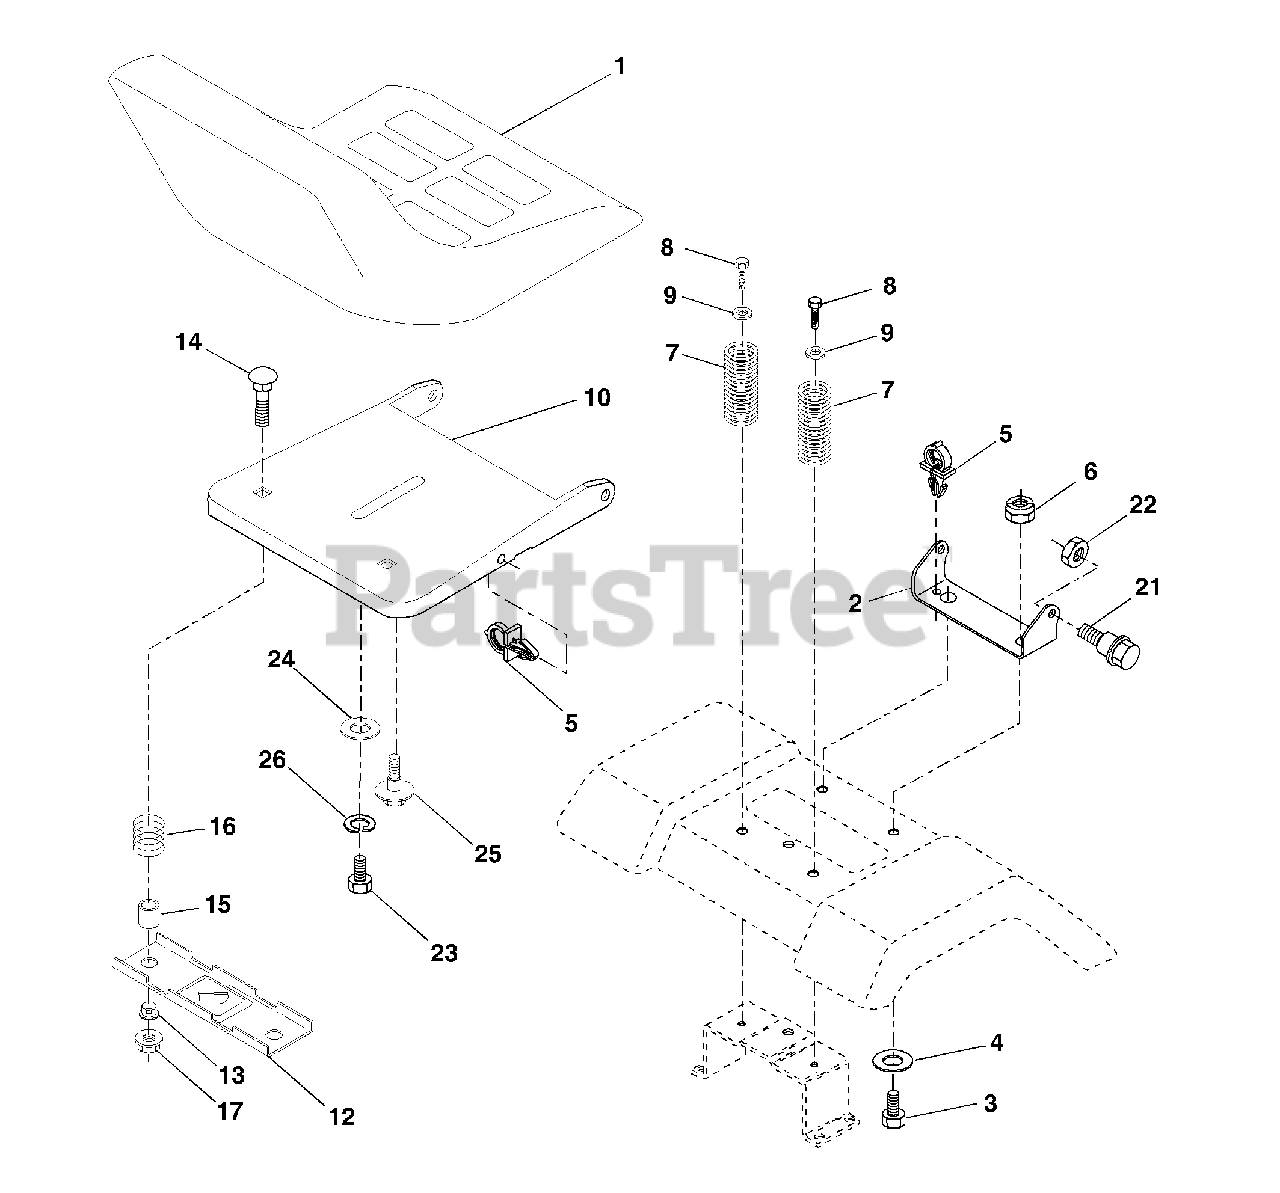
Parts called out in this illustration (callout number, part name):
1	Seat
2	Bracket Pnt Pivot Seat(blk )
3	Bolt
4	Washer 13/32 x 1 x 10 Ga
5	Clip Push-In Hinged
6	Nut
7	Spring Seat Cprsn 2 250 Blk Zi
8	Screw 3/8-16 x 1.5
9	Washer 13/32 x 1 x 14 Ga
10	Pan Pnt Seat (blk )
12	Bracket Pnt Mounting Switch
13	Bushing Snap Blk Nyl 50 Id
14	Bolt Rdhd Sht Nk 1/4-20 x 1-1/2
15	Spacer Split 28 x 96 Yel Zinc
16	Spring Cprsn 1 27 Blk Pnt
17	Nut Lock 1/4 Lge Flg Gr 5 Zinc
21	Bolt Shoulder 5/16-18 Unc Blkz-2A
22	Nut
23	Bolt Hex Black
24	Washer 17/32 x 1-3/16 x 12 Ga
25	Bolt Shoulder 5/16-18 x 62
26	Lockwasher
